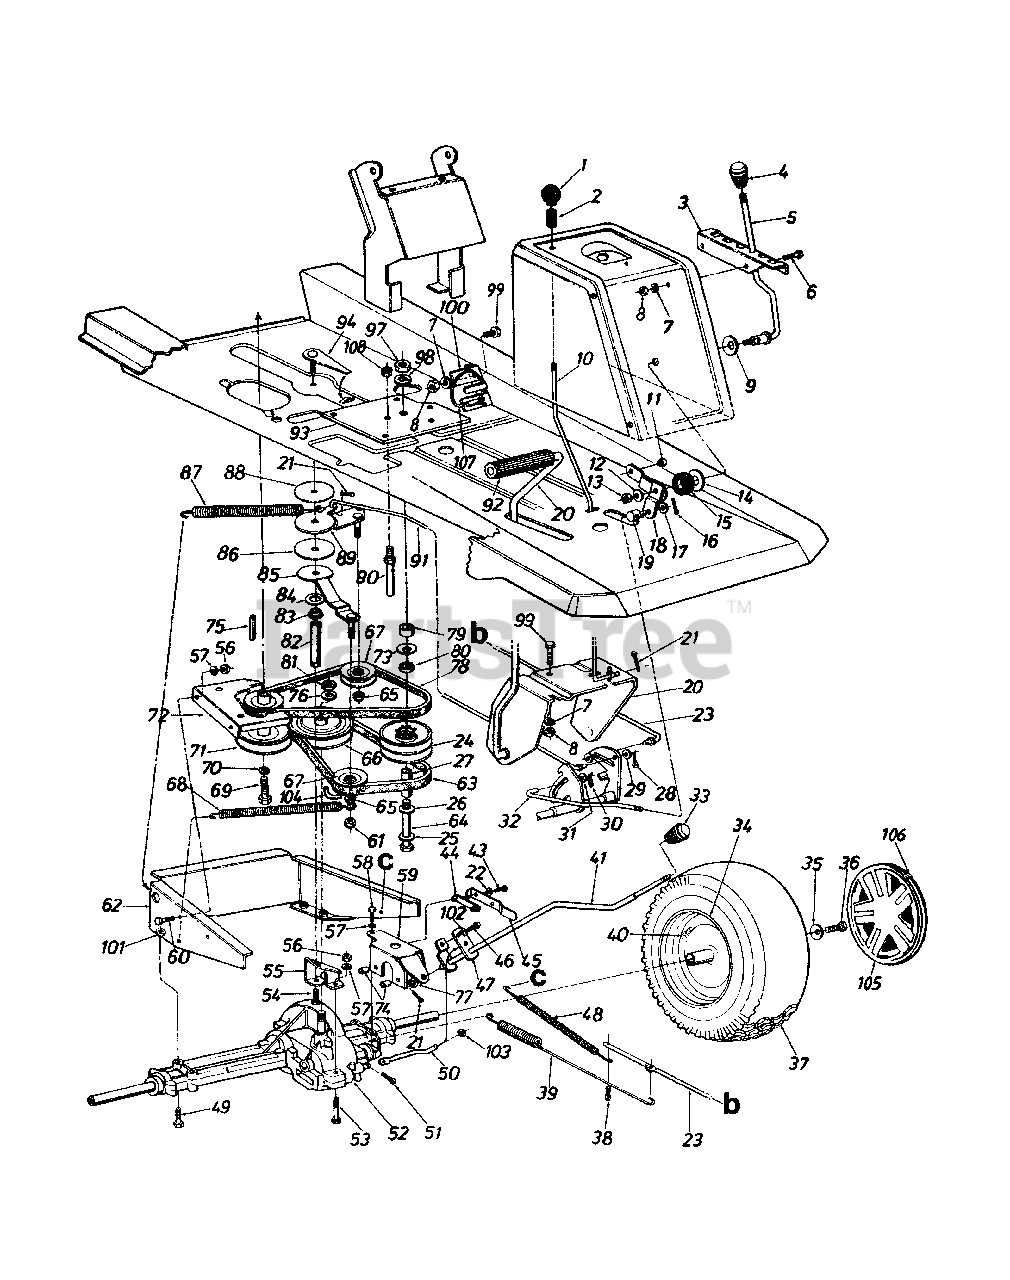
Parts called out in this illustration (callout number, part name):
1	Ball Knob 1/4-20 Thd. 1.25"
2	Compression Spring
5	Speed Control Lever
6	Truss Mach. Scr. 5/16-18 x .75"
7	L-Wash. 5/16" I.D.
8	Hex Nut 5/16-18 Thd.
9	Bell-Wash. .345" I.D. x .88"
10	Brake Locking Rod
12	Bell-Wash. .345" I.D. x .08"
13	Hex Cent. L-Nut 5/16-18 Thd.
14	Fl-Wash. .531" I.D. x 1.25" O.D.
15	Rubber Washer
16	Intern. Cotter Pin 1/2" Dia.
17	Fl-Wash. .34" I.D. x .68" O.D.
18	Speed Control Lever Brkt. Ass'y.
19	Ferrule-Engagement
20	Clutch/Brake Pedal Ass'y.
21	Cotter Pin 3/32" Dia. x .75"
22	Plastic Washer
23	Brake Rod
24	Variable Speed Pulley Ass'y.
25	Fl-Wash. .4" I.D. x 1.25" O.D.
26	Thrust Brg. 1.25" O.D. x .56"
27	Spacer Sleeve 2.71"
28	Cotter Pin 1/8" Dia. x 1.25"
29	Fl-Wash. .34" I.D. x .60" O.D.
30	Intern. Cot-Pin 5/16" Dia.
31	Fl-Wash. .34" I.D. x .60" O.D.
32	Speed Control Link
33	Shift Knob
35	Bell-Wash. .345" I.D. x .88"
36	Hex L-Bolt 5/16-24 x .75" Lg.
38	Cotter Pin 1/8" Dia. x 1.25"
39	Extension Spring 17.0" Lg.
40	Air Valve
44	Insulator Nut
45	Spring Switch
46	Hex Bolt 1/4-20 x .50" Lg.
47	Shift Lever Adjusting Link
48	Ext. Spring 81/4" Lg.
49	Hex Bolt 5/16-18 x 2.5" Lg.
50	Shift Rod
51	Intern. Cotter Pin
52	Transaxle
53	Hex Bolt 1/4-20 x 1.75" lg.
54	Hex Bolt 3/8-24 x .75" Lg.
57	L-Wash. 1/4" I.D.
58	TT-Tap Scr. 1/4-20 x 1.5" Lg.
59	Shift Lever Support Brkt.
60	Hex Bolt 1/4-20 x 1.00" Lg.
61	Hex L-Nut 3/8-24 Thd.
64	Hex Bolt 3/8-16 x 4.5" Lg.
65	Hex Ins. L-Nut 3/8-24 Thd.
66	V-Pulley
67	V-Belt Idler .38" I.D. x 3.06"
68	Ext. Spring .50" O.D. x 6.37"
69	Hex Bolt 7/16-20 x 1.00" Lg.
70	L-Wash. 7/16" I.D.
71	Engine Pulley
72	Upper Eng. Belt Guard
73	Bell-Wash. .4" I.D. x 1.12" O.D.
74	Spacer .256" I.D. x .50" O.D.
75	Sq.-Key 1/4" x 2.00" Lg.
76	Bell-Wash. .567" I.D. x 1.125"
77	Fl-Wash. .469" I.D. x .88" O.D.
78	V-Belt
79	Spacer 1.00" x .380" O.D.
80	Thrust Wash. .56" I.D. x 1.25"
81	Hex Jam Nut 9/16-18 Thd.
82	Torque Rod
83	Flange Bearing .378
84	Fl-Wash. .640" I.D. x 1.24"
85	Idler Bracket Ass'y.
86	Thrust Wash. .635" I.D.
87	Extension Spring 7.58" Lg.
88	Thrust Wash. .385" I.D.
89	Idler Bracket Ass'y. For Clutch
90	Belt Guard Pin 3/8-16 x 2.75" Lg.
91	Clutch Rod
92	Foot Pad
98	L-Wash. 3/8 Heavy Duty
99	Hex Bolt 5/16-18 x .75" Lg.
100	Speed Control Rod Brkt.
101	Hex Sems Nut 5/16-18 Thd.
102	Bell-Wash. .265" I.D. x .75" O.D.
103	Push on Retaining Ring
104	Belt Guard
105	Hub Cap-Beige
106	Spring Clip
107	Comp. Spring Clip
108	Hex Top L-Jam Nut 3/8-16 Thd.
